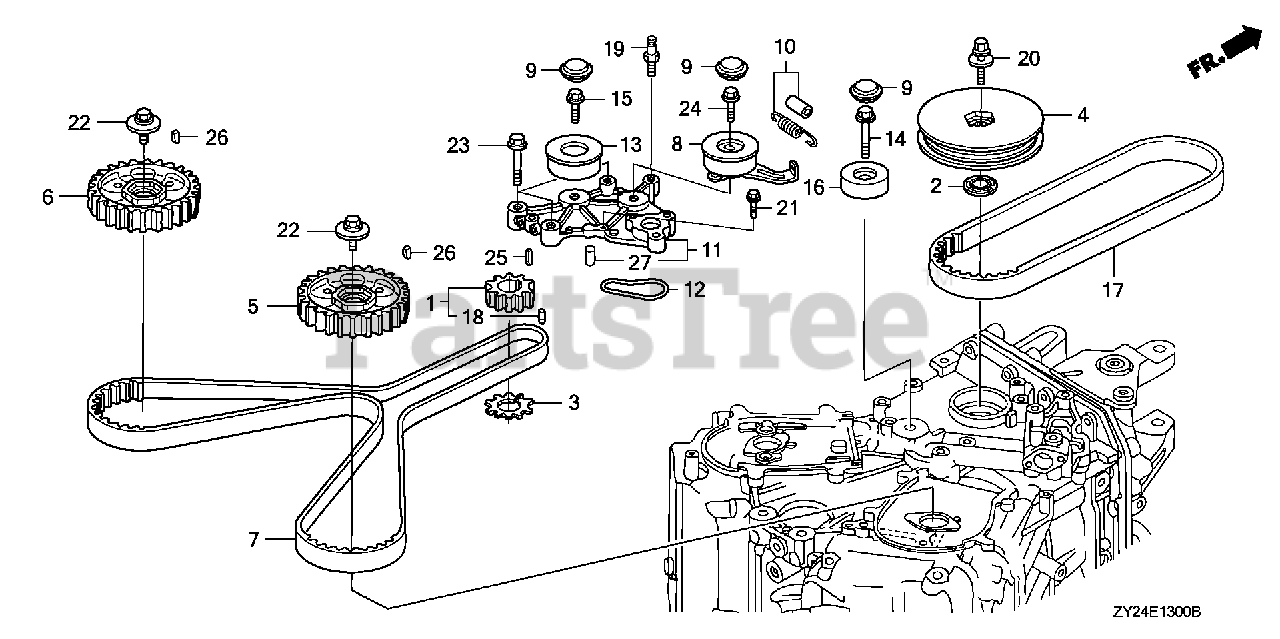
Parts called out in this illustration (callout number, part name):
1	PULLEY, TIMING BELT DRIVE
2	PLATE, TIMING BELT GUIDE
3	PLATE, TIMING BELT GUIDE
4	PULLEY, CRANKSHAFT
5	PULLEY, R. TIMING BELT DRIVEN
6	PULLEY, L. TIMING BELT DRIVEN
7	BELT, TIMING (197YU26 GB-323)
8	TENSIONER, TIMING BELT
9	CAP, TIMING BELT TENSIONER
10	SPRING, TIMING BELT ADJUSTING
11	BASE, TIMING BELT TENSIONER *NH8* (DARK GRAY)
12	O-RING, TIMING BELT TENSIONER BASE
13	IDLER, TIMING BELT (KOYO SEIKO)
14	BOLT, IDLER
15	BOLT, TIMING BELT IDLER A
16	IDLER B, TIMING BELT
17	BELT, ALTERNATOR (6PK745 M-180)
18	PIN, VERTICAL SHAFT
19	BOLT, TIMING BELT ADJUSTING SPRING
20	BOLT-WASHER (16X49)
21	BOLT, FLANGE (6X22)
22	BOLT-WASHER (12X35)
23	BOLT, FLANGE (10X40)
24	BOLT, FLANGE (10X43)
25	KEY (4.5X38.5)
26	KEY, SPECIAL
27	PIN, DOWEL (6X10)
